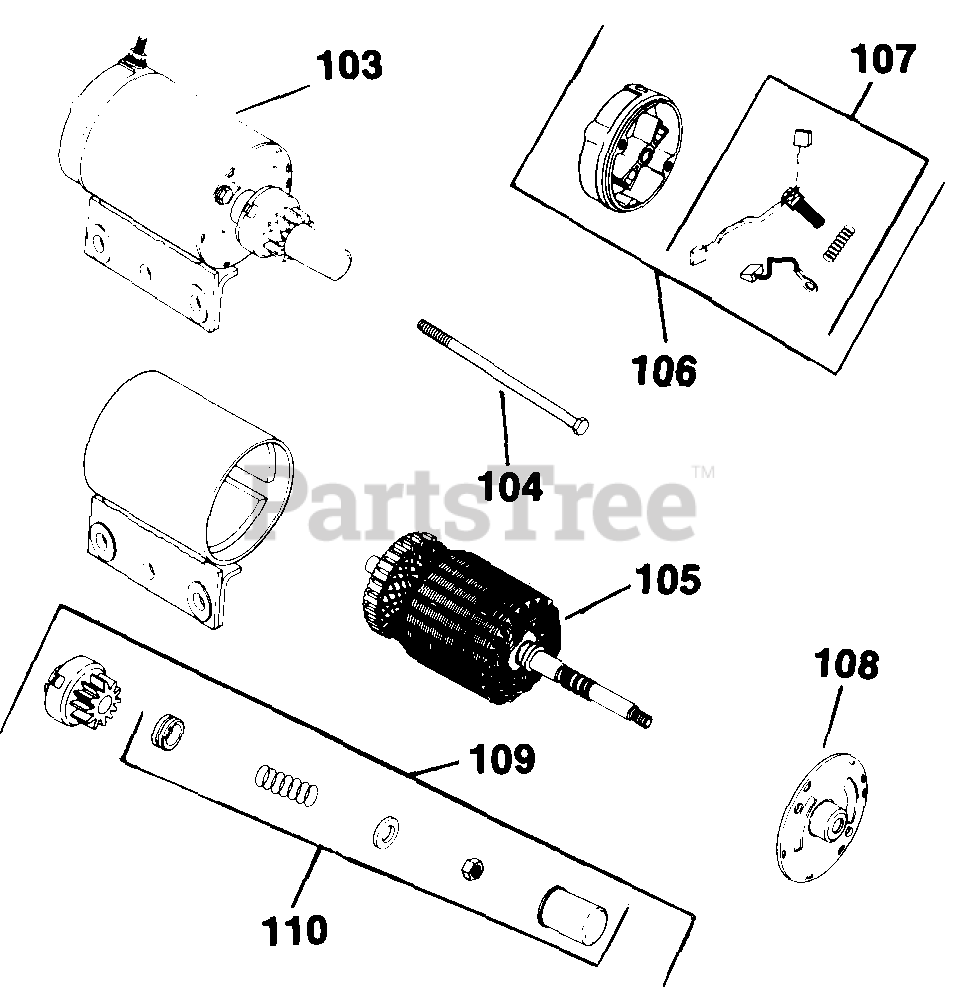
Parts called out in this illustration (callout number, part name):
103	STARTER - USE 45 098 03
105	KIT, ARMATURE - DISCONTINUED
106	CAP - DISCONTINUED
107	KIT - USE 52 755 15
108	CAP - USE 45 081 05
109	STARTER - USE 45 098 09
110	HEAD - USE 45 015 09
